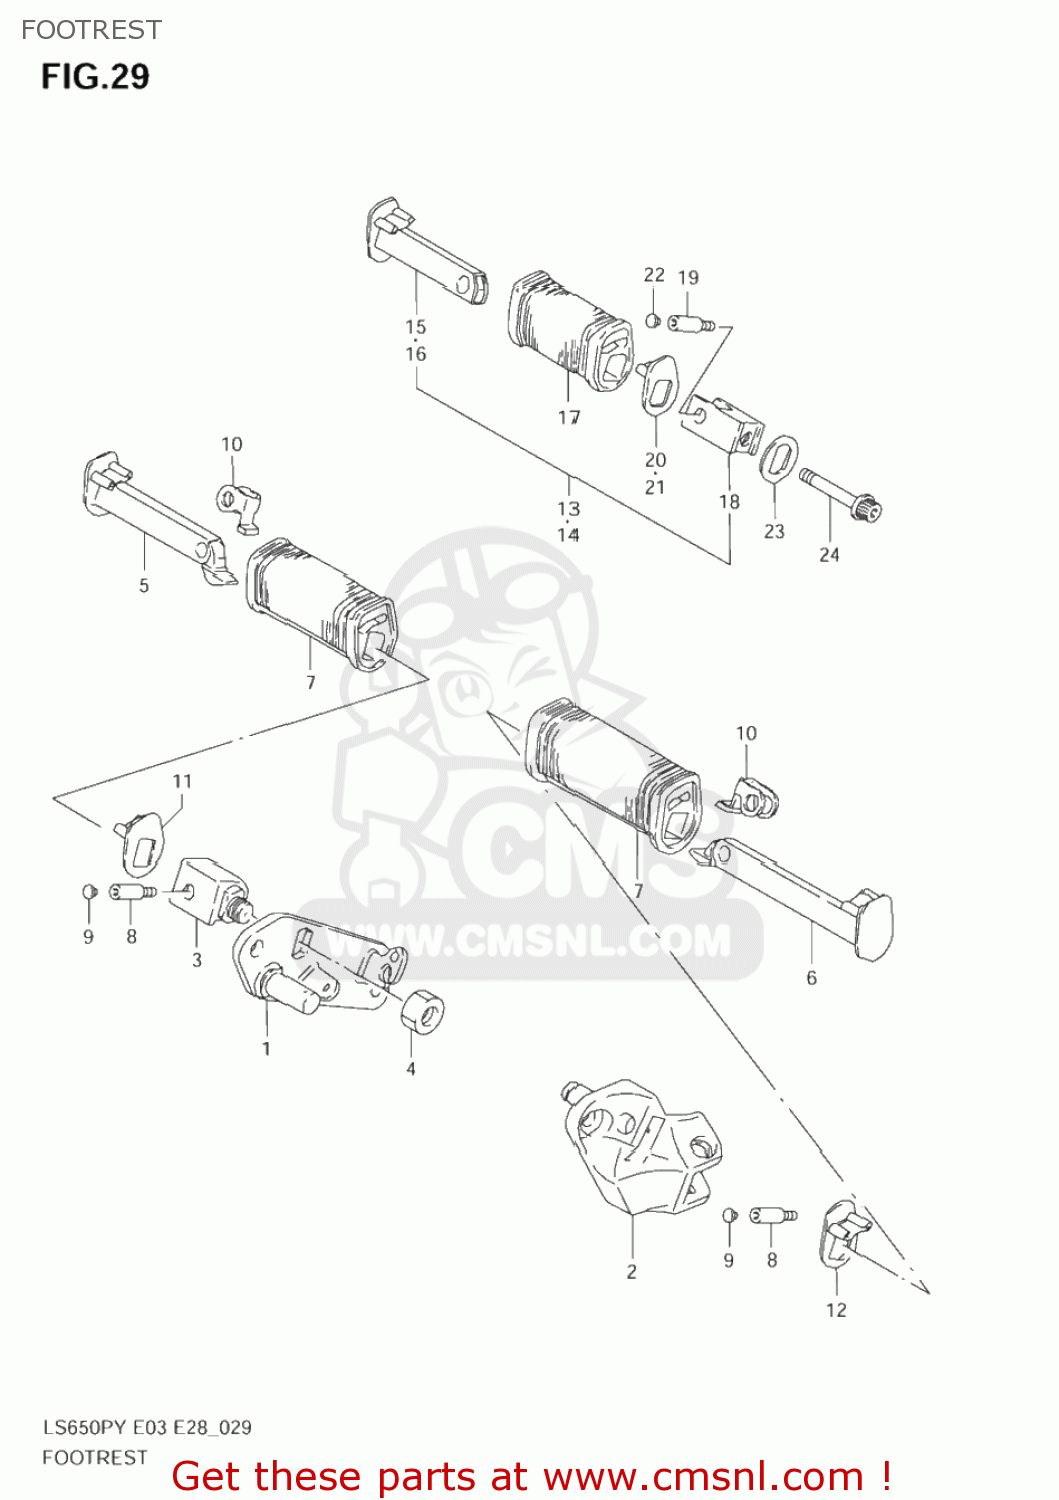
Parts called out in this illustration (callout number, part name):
1	BRACKET,FR FOOTREST,R
2	BRACKET,FR FOOTREST,L
3	HOLDER,FR FOOTREST,R
4	NUT
5	BAR,FR FOOTREST,R
6	BAR,FR FOOTREST,L
7	RUBBER,FR FOOTREST
8	BOLT(6X8)
9	CAP,PILLION FOOTREST BOLT
10	CUSHION,FR FOOTREST
11	WASHER,FR FOOTREST,R
12	WASHER,FR FOOTREST,L
13	FOOTREST ASSY,PILLION,R
14	FOOTREST ASSY,PILLION,L
15	BAR,PILLION FOOTREST,R
16	BAR,PILLION FOOTREST,L
17	RUBBER,PILLION FOOTREST
18	HOLDER,PILLION FOOTREST
19	BOLT(6X8)
20	WASHER,FR FOOTREST,R
21	WASHER,FR FOOTREST,L
22	CAP,PILLION FOOTREST BOLT
23	WASHER,PILLION FOOTREST HOLDER
24	BOLT
